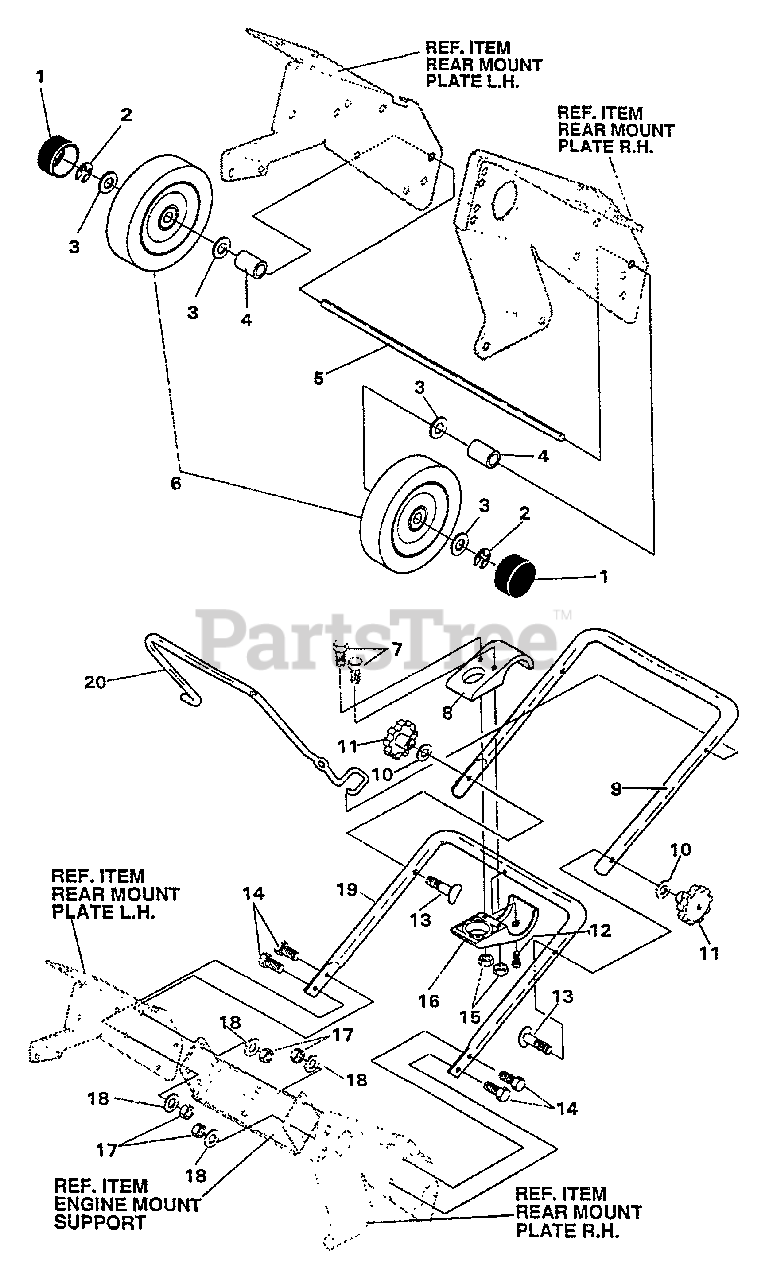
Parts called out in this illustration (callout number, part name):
1	CAP, HUB
2	RING, RETAINING
3	WASHER
4	SPACER, SLEV .407X.63X.440
5	SHAFT, AXLE 5/21
6	WHEEL ASSY
7	SCREW - 10-24 X 1.00"
8	BRKT HALF, CHUTE CRANK
9	HANDLE - UPPER
10	WASHER
11	KNOB KIT
12	SCREW - 1/4-20 X .63" -- TAPPING
13	BOLT, 5/16-18 X 2.00
14	SCREW - 5/16-18 X 3/4"
15	LOCKNUT - 10-24
16	BRKT HALF, CHUTE CRANK
17	NUT - 5/16-18
18	WASHER
19	HANDLE - LOWER
20	BAR, CONTROL DRIVE .31 DIA.
